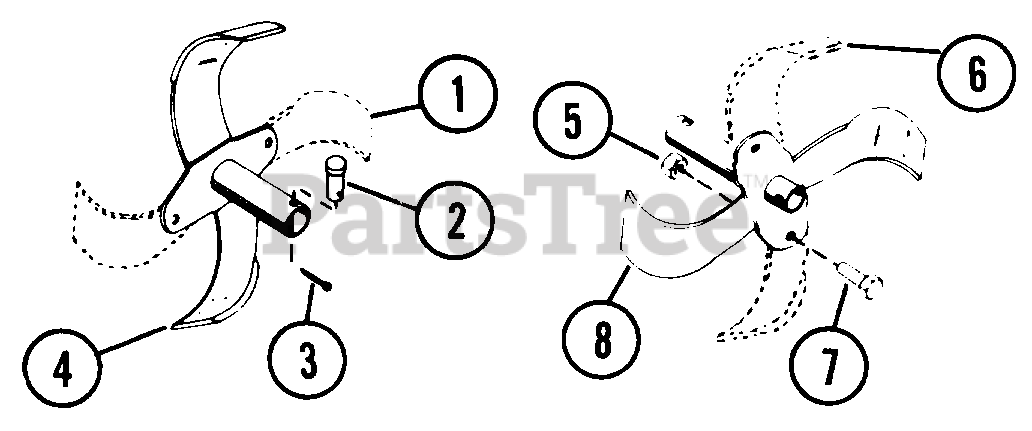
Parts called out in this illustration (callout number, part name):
1	R H TURBO-TINE
2	CLEVIS PIN
3	PIN-HAIR INT .08X.38X1.42 YWZC
4	R H TINE SPOOL
5	NUT-LK-TOP .437-14 GR C PL
6	L H TURBO-TINE
7	BLT-HEX .44-14X1.00 GR5
8	L H OUT TINE SPOOL
